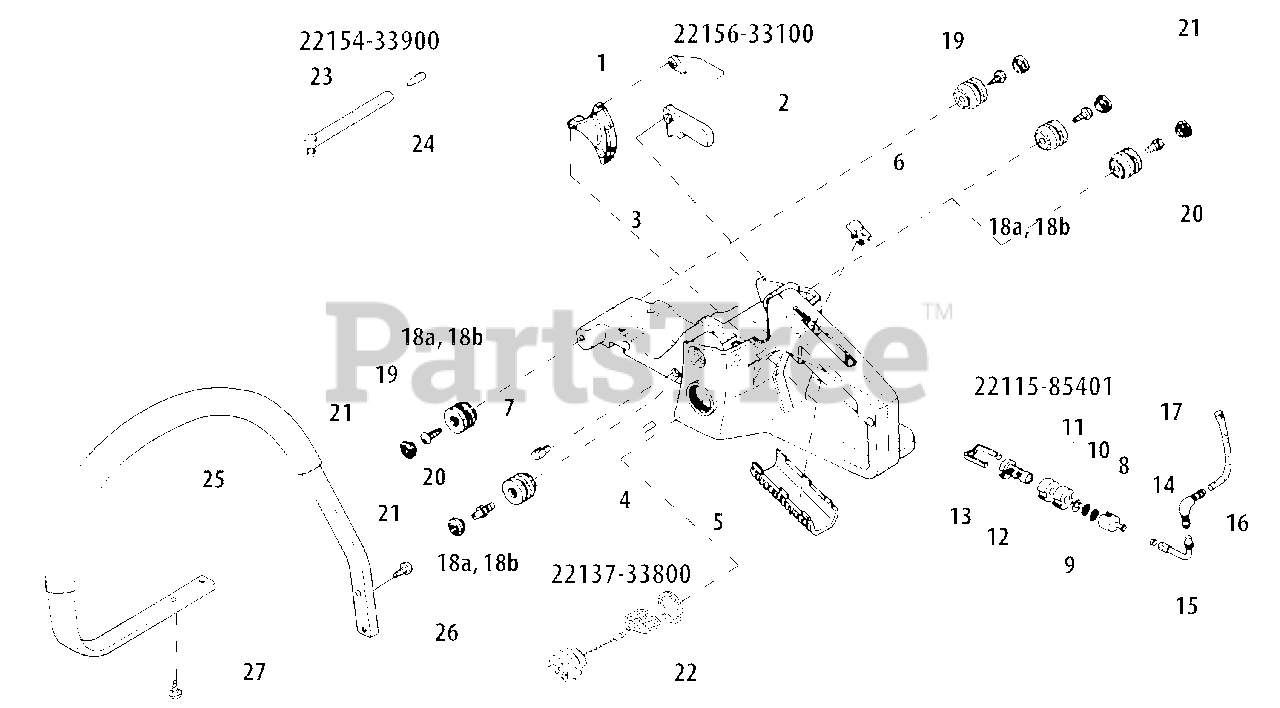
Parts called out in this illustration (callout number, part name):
1	LEVER, LOCK
2	SPRING, LEVER
3	TRIGGER, THROTTLE
4	PIN - 4X25
5	GRIP
6	STOPPER
7	CUSHION
8	WEIGHT, FUEL FILTER
9	SCREEN, FILTER
10	RING, RETAINING
11	FILTER, FUEL
12	CASE, FILTER
13	CLIP, FILTER
14	RING, RETAINING - 6
15	PIPE - FUEL
16	JOINT
17	PIPE - FUEL
19	BOLT
20	BOLT
21	PLUG - 22
22	GASKET
23	PIPE - BREATHER
24	ELEMENT, BREATHER
25	HANDLE - FRONT
26	SCREW - 5X21
27	SCREW - 5X17
22115-85401	FILTER, FUEL
22137-33800	CAP ASSY
22154-33900	VENT, FUEL TANK
22156-33100	HANDLE ASSY - REAR
